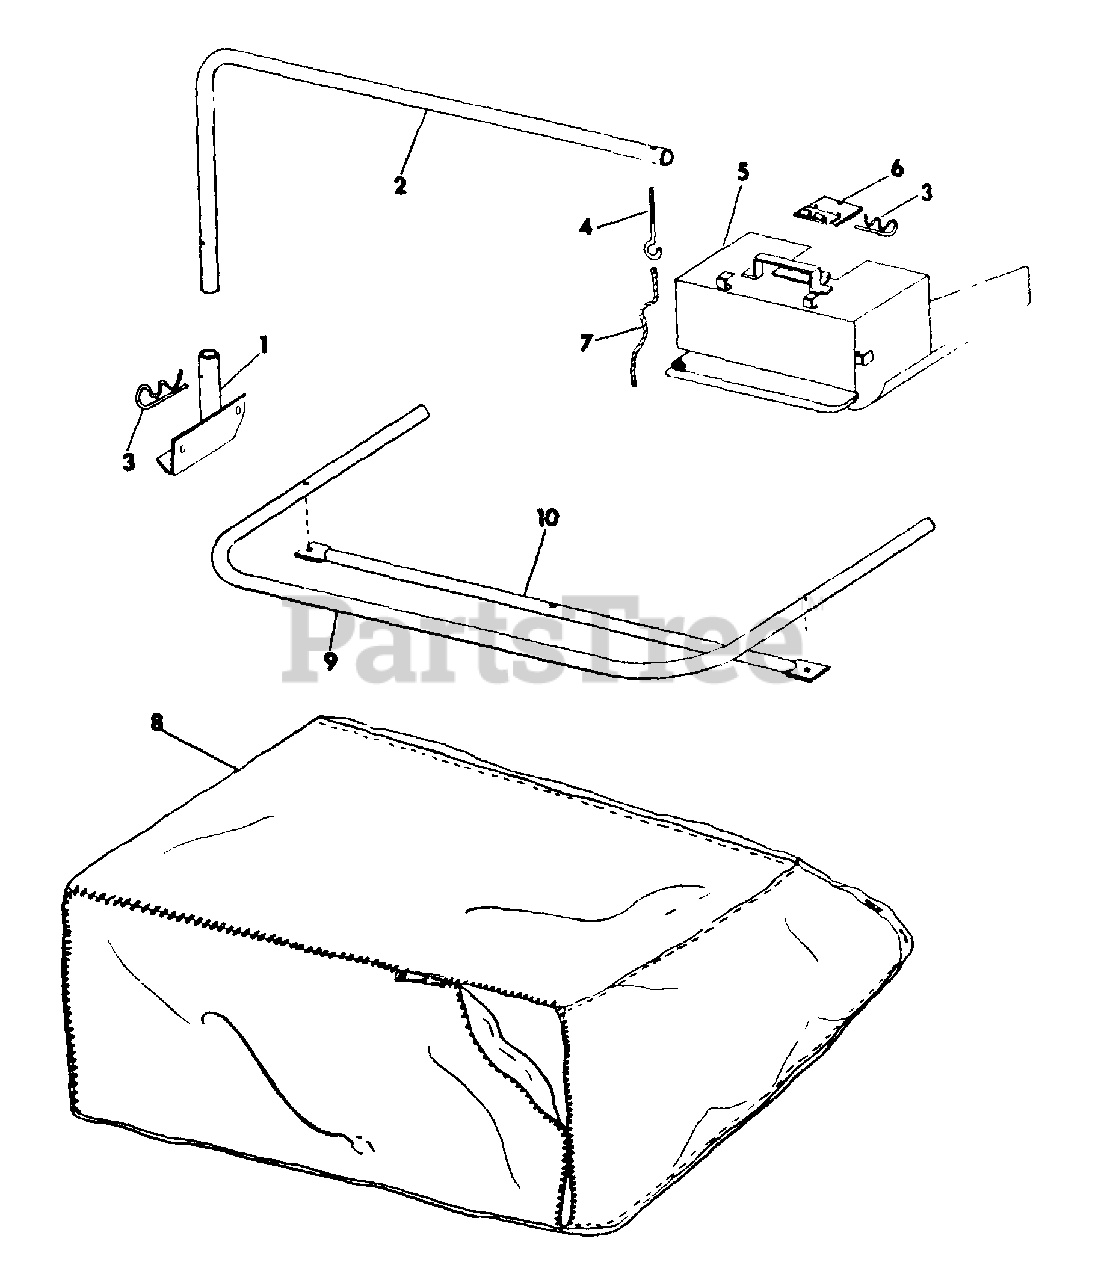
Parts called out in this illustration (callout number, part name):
1	BRACKET, MTG
2	PIPE, SUPPORT
4	EYEBOLT, NO 10
7	ROPE, BAG ATTACHMENT
9	PIPE, SUPPORT
10	PIPE, CROSS TIE
